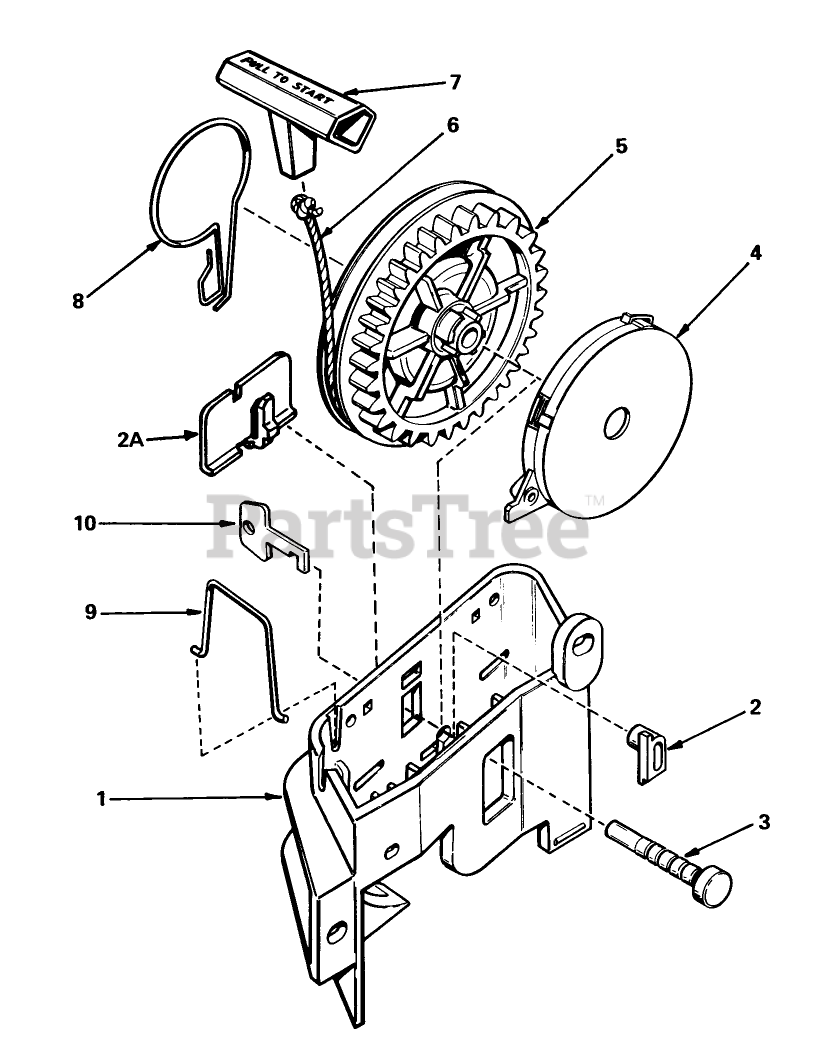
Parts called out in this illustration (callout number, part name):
1	Bracket Starter
2	Pawl, Locking Not used on all engine models)
2A	Clip, Starter Bracket (Used On Starters Not Equipped With Pawl, Ref. No. 2)
3	Pin-Pulley
4	Spring Assy., Rewind (Incl. Ref. #3)
5	Pulley
6	Rope Starter (Length 65" 9/64" Dia.)
7	Handle-Starter
8	Brake
9	Clip-Rope
10	Key (Not Used On All Engine Models
